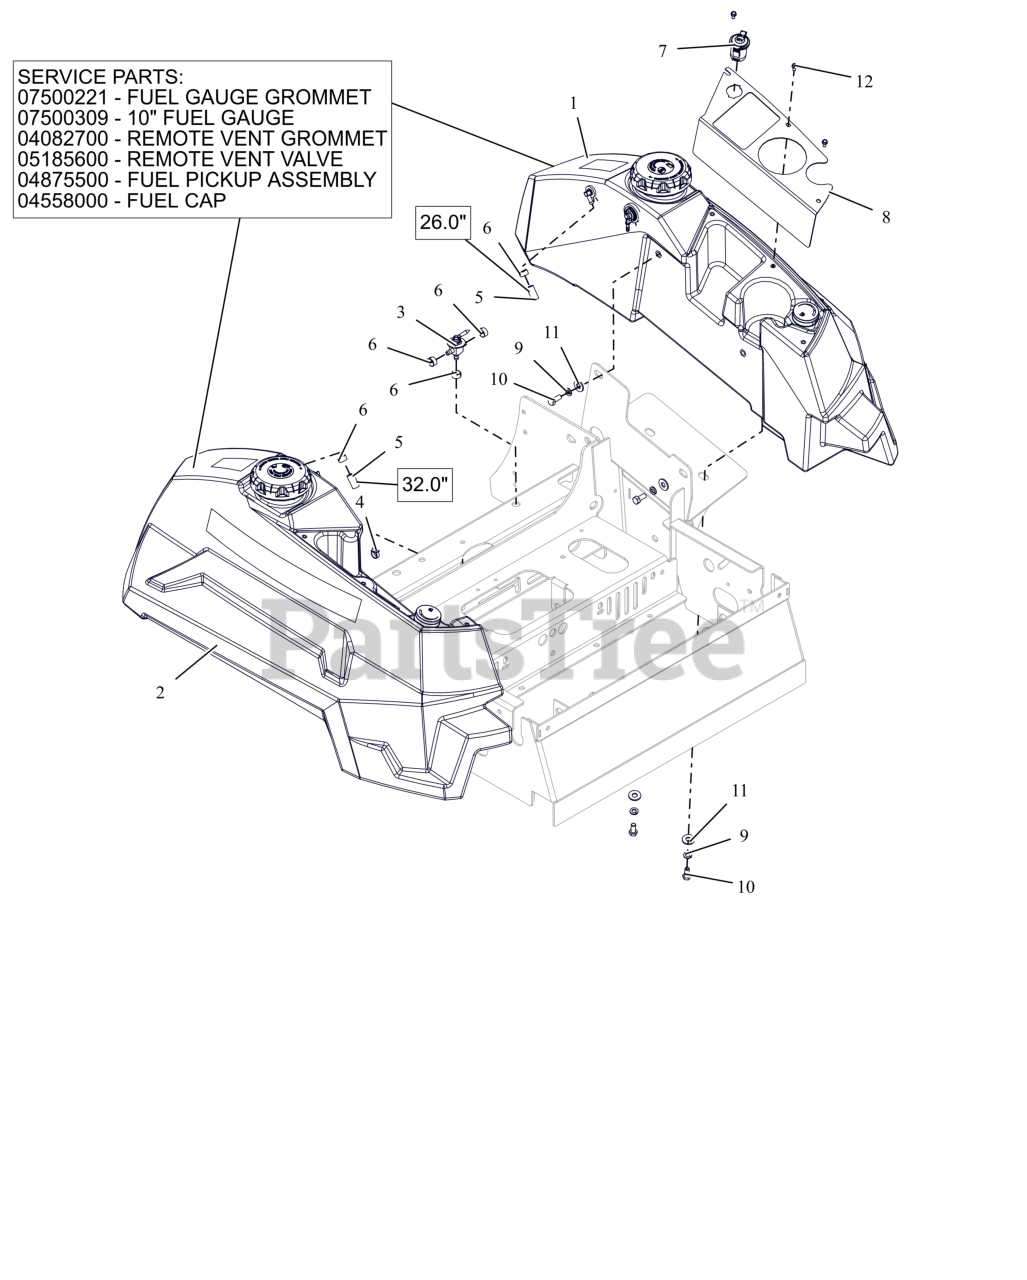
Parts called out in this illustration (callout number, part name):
1	ASM, LH FUEL TANK
1	GROMMET, FUEL GAUGE
1	GAUGE, REMOTE FUEL SEALED 10"
1	GROMMET, REMOTE VENT NITRILE
1	VALVE, COMBINATION VENT 3/16
1	ASSM,LRG TANK FUEL PICKUP LINE
1	CAP, FUEL VENTIN AUTOLOCK
2	ASSY-RH, PT400 FUEL TANK
2	GROMMET, FUEL GAUGE
2	GAUGE, REMOTE FUEL SEALED 10"
2	GROMMET, REMOTE VENT NITRILE
2	VALVE, COMBINATION VENT 3/16
2	ASSM,LRG TANK FUEL PICKUP LINE
2	CAP, FUEL VENTIN AUTOLOCK
3	VALVE - FUEL
4	ROUTING CLIP (1/2" ID)
5	HOSE, .25 LOW-PERM BULK GAS
6	CLAMP, FUEL LINE
7	PORT, 12 VOLT POWER
8	CUP HOLDER/POCKET PLATE - RED
9	WSHR,LK-REG .312X.078 ZCC
10	BLT,HEX .31-18X.75 G5 ZCC
11	WSHR,FLT .375X.875X.083 ZCC
12	SCR-MCH 10-24X.38 HWHSTAINLESS
